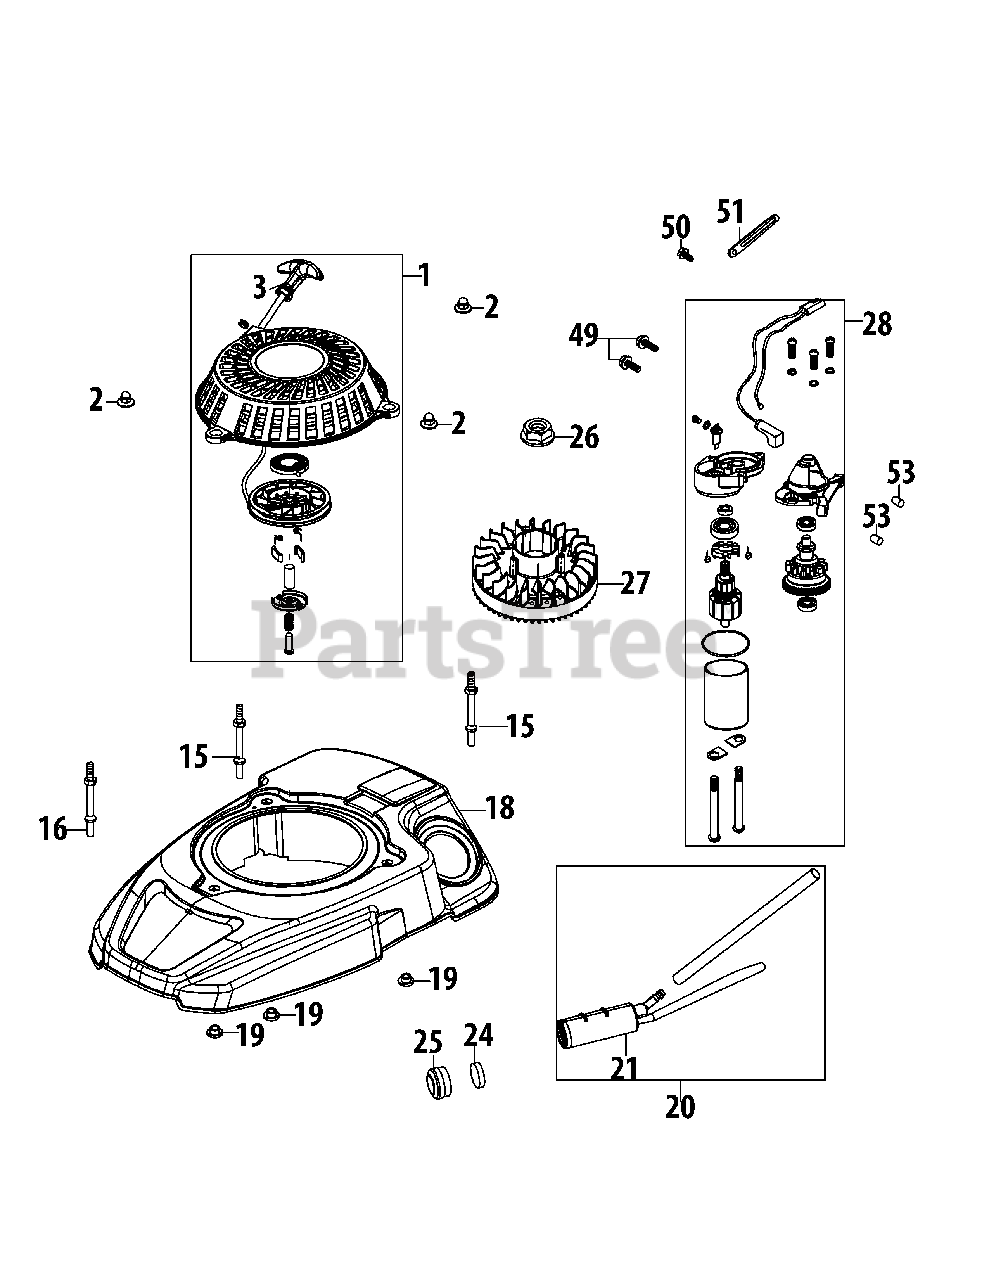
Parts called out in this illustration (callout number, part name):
1	Recoil Starter Assembly
2	Starter Acorn Nut
3	Starter Handle
15	Starter/Shroud Rear Stud M6×78.5
16	Starter/Shroud Front Stud M6×74
18	Engine Shroud
19	Engine Shroud Spacer
20	Carbon Canister Assembly
21	Carbon Canister
24	Carbon Canister Filter
25	Carbon Canister Filter Cap
26	Flywheel Nut M14
27	Flywheel
28	Electric Starter Assembly (53:9)
49	Bolt M6X28 T/X/P Crankcase/Dp Stick
50	Bolt M6X12 Multi-Purpose
51	Flexible Clamp, Vent Hose
53	Starter Housing Dowel Pin 8×8
